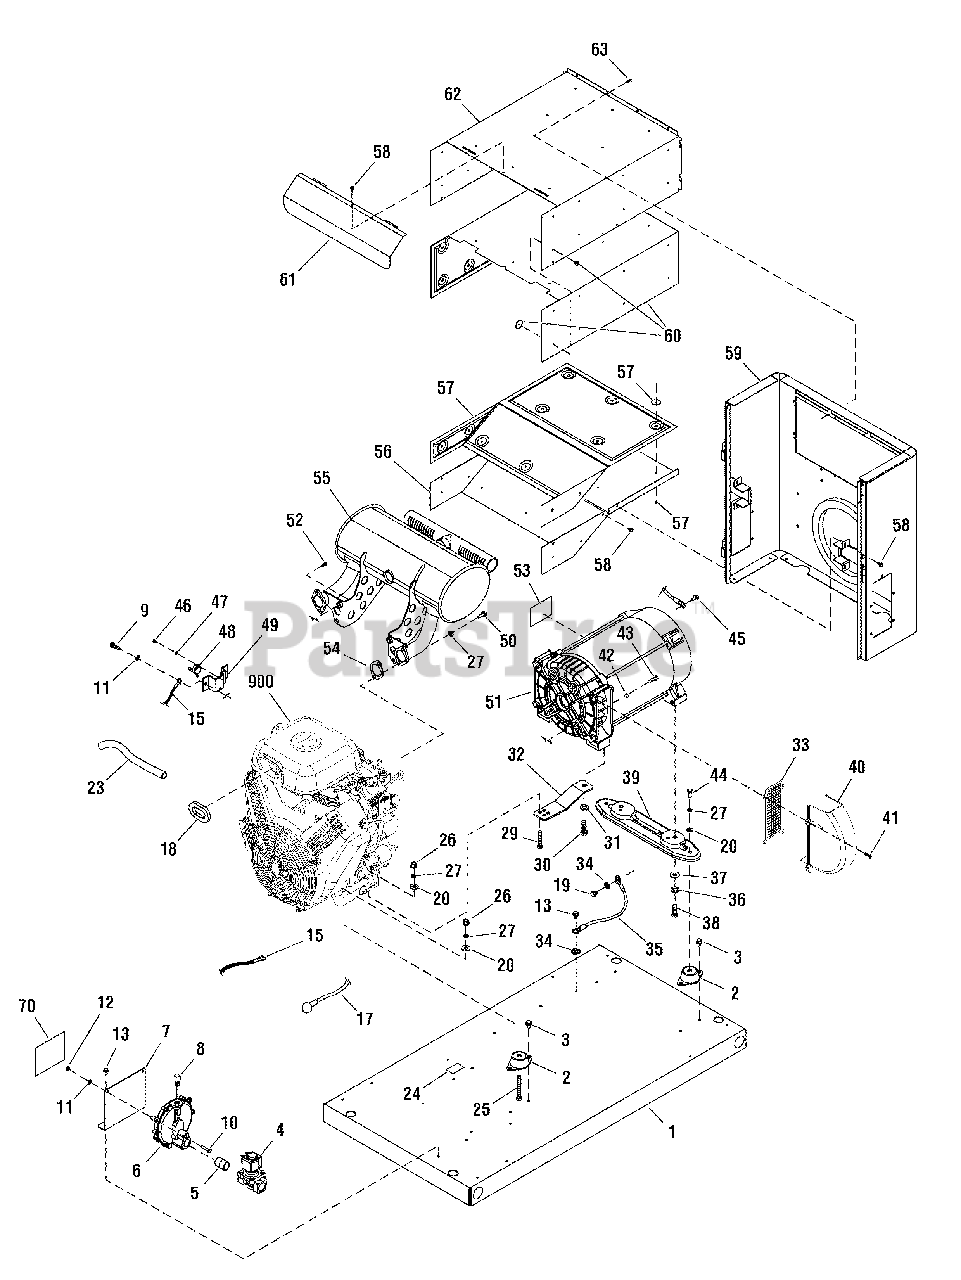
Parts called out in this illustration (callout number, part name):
2	MOUNT, Vibration
4	SOLENOID, Gas Fuel
6	REGULATOR, NG/LPG
7	BRACKET
9	* CAPSCREW, Hex Head, M6-1 x 16
10	* CAPSCREW, Hex Head, M6-1 x 30
11	* WASHER, Lock, 1/4
12	* NUT, M6-1
13	BOLT
15	CABLE, Battery, Black
17	CABLE, Battery, Red
18	SEAL, Foam
20	* WASHER, Flat, 5/16-M8
23	HOSE, Oil Drain
24	DECAL, Oil Drain
25	* CAPSCREW, Hex Head, 5/16-18 x 2-1/2
26	* NUT, 5/16-18
27	* WASHER, Lock, 5/16-M8
29	* CAPSCREW, Hex Head, 5/16-18 x 2
30	* CAPSCREW, Hex Head, M12-1.75 x 35
31	* WASHER, M12
32	SUPPORT, Engine
34	* WASHER, Shakeproof, M6-1/4
36	* WASHER, Lock, 3/8
37	* WASHER, Flat, 3/8
38	* CAPSCREW, Hex Head, 3/8-16 x 1
39	SUPPORT, Engine
41	* SCREW, Taptite, M5-0.8 x 10
42	* WASHER, Lock, 3/8
43	* CAPSCREW, Socket Head, 3/8-16 x 1-1/4
44	* CAPSCREW, Hex Head, 5/16-18 x 3/4
45	BOLT
46	* SCREW, Phillips Head, 4-40 x 3/16
47	* WASHER, Lock, #4
49	PLATE, Temp Switch
50	SCREW
51	ALTERNATOR
53	DECAL
59	BULKHEAD, Alternator
62	BOX, Muffler Top
900	** ENGINE
